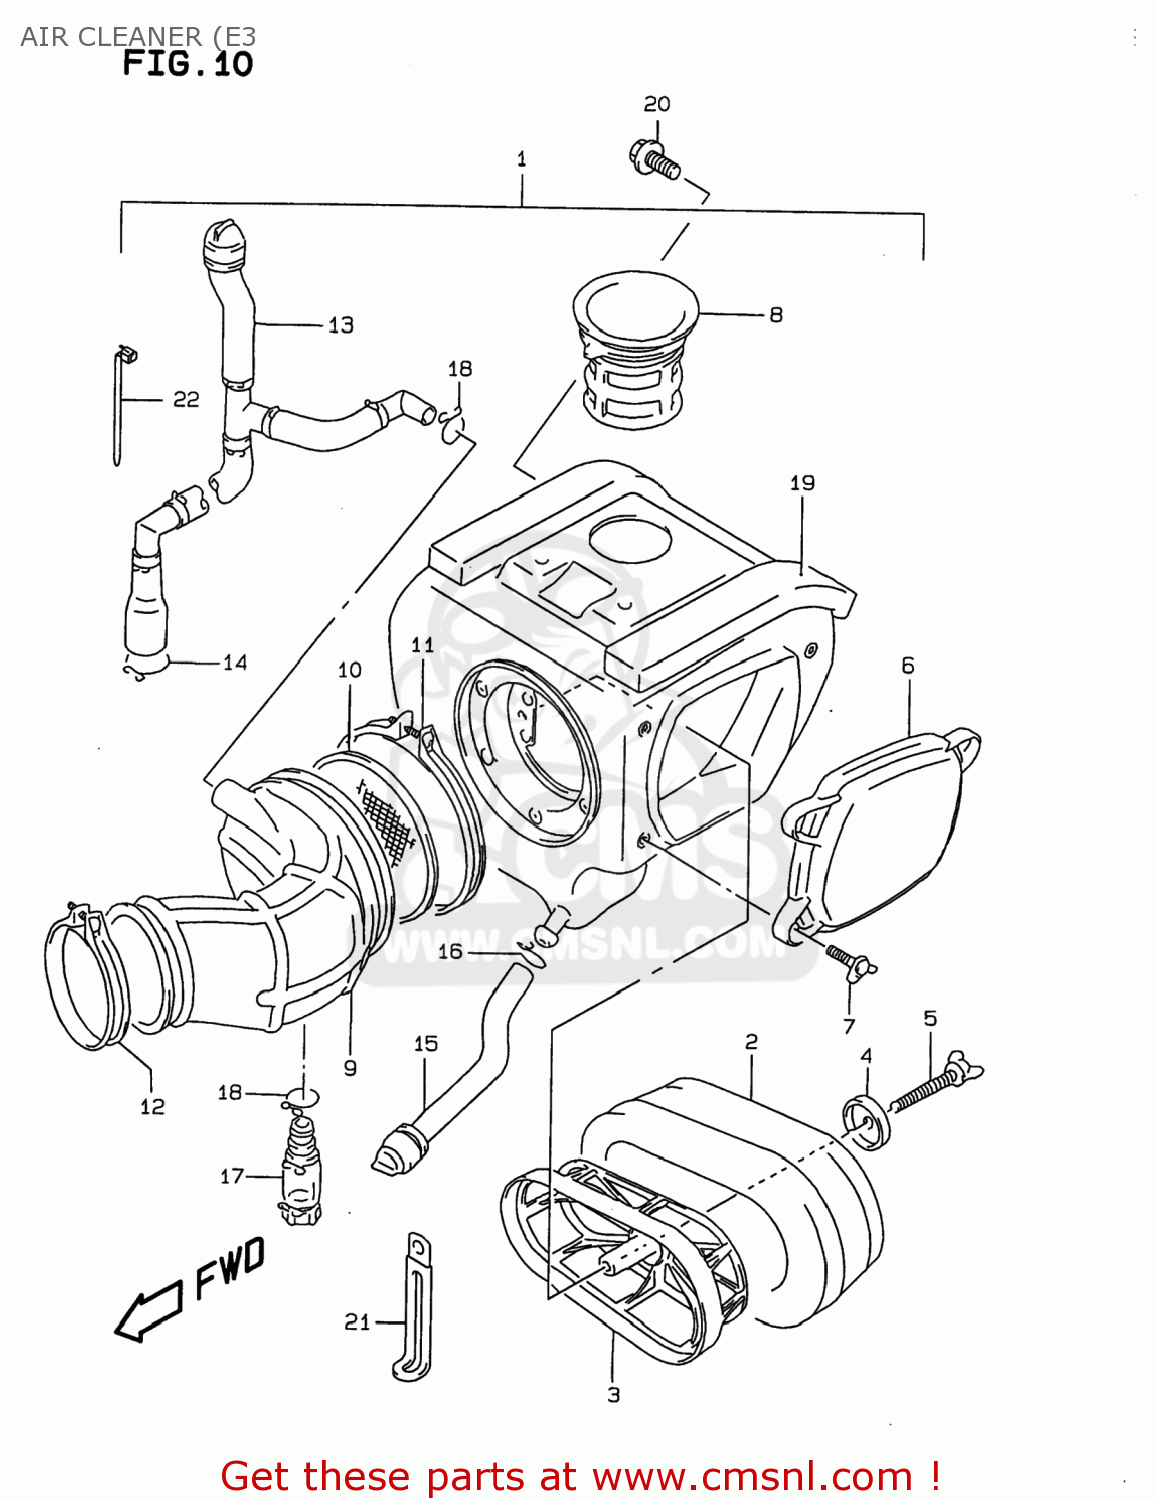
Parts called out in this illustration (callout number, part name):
1	CLEANER ASSY,AIR
2	FILTER
3	HOLDER,FILTER
4	WASHER,AIR CLEANER
5	BOLT,WING
6	CAP,AIR CLEANER
7	SCREW
8	TUBE,INLET
9	TUBE,OUTLET
10	TRAP,FRAME
11	CLAMP,OUTLET TUBE
12	CLAMP
13	TUBE,BREATHER
14	CLIP
15	TUBE,DRAIN A
16	CLIP
17	TUBE,DRAIN
18	CLIP
19	CUSHION
20	BOLT
21	CLAMP(L:80)
22	CLAMP(L:165)
